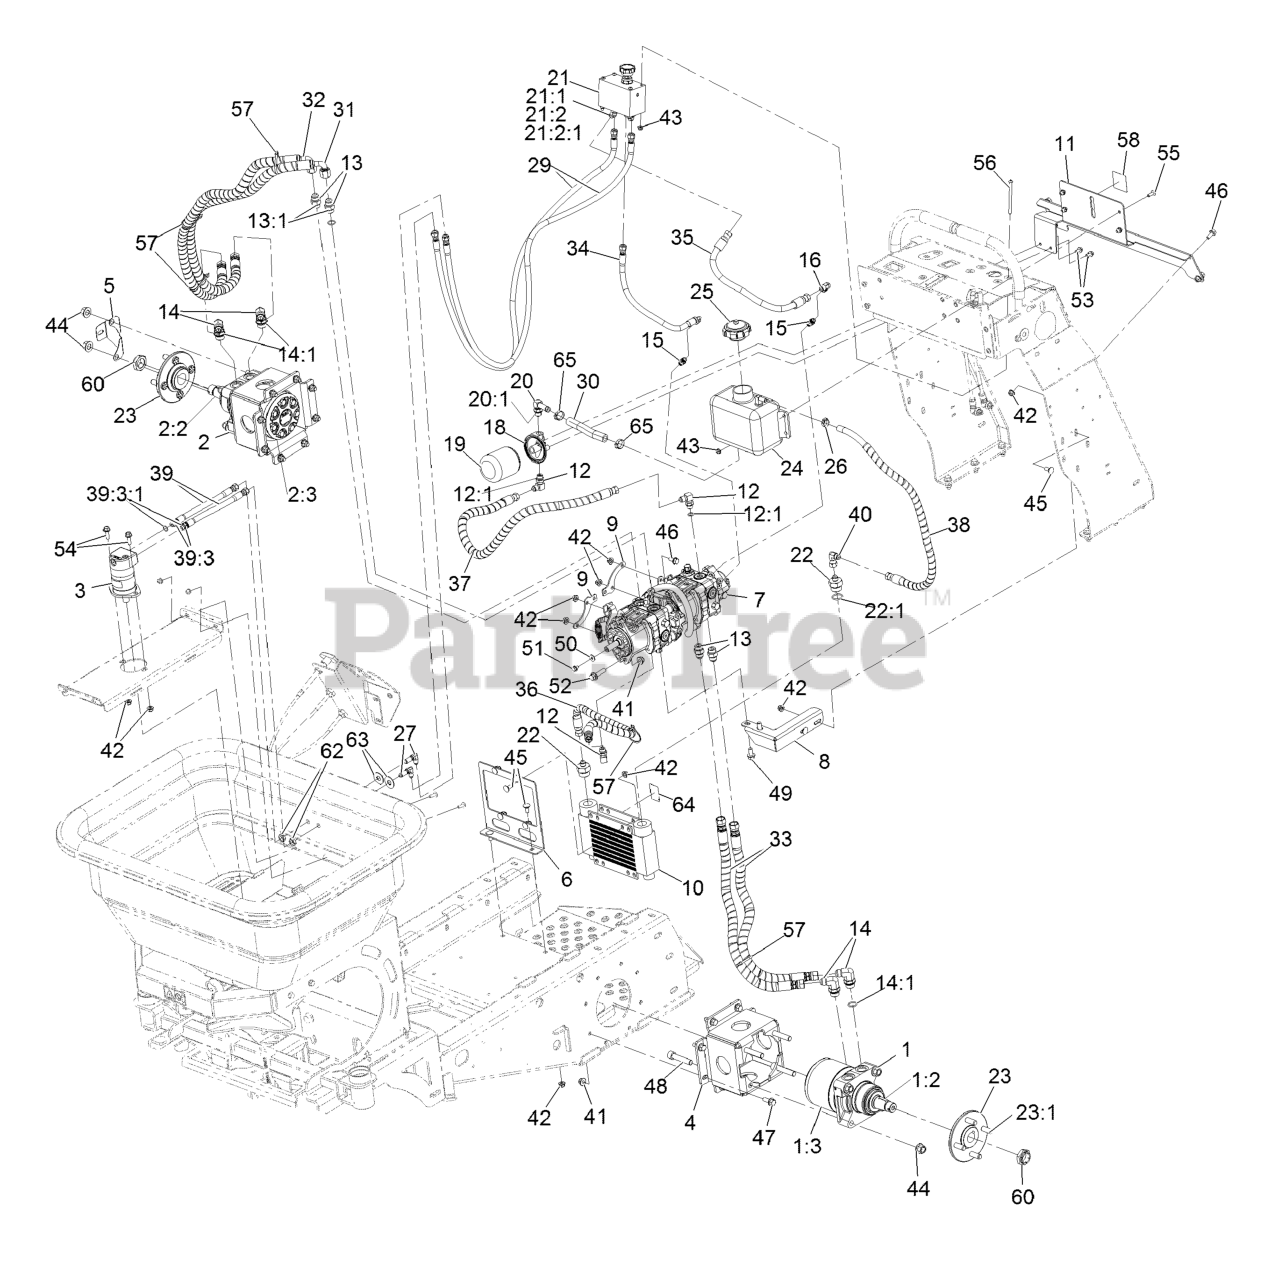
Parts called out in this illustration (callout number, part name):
1	MOTOR, LH WHEEL
1:2	KEY-WOODRUFF
1:3	SEAL KIT
2	MOTOR, RH WHEEL
2:2	KEY-WOODRUFF
2:3	SEAL KIT
3	MOTOR-HYDRAULIC, SPREADER
4	Mount-Motor, Wheel [black]
5	BRACKET-HOPPER, SPEEDOMET
6	Mount-Cooler
7	PUMP-TANDEM
8	Bracket-Support, Hydro Pump
9	Extension, Hydro Pump
10	COOLER-OIL
11	Mount, Hydraulic Tank And Filter
12	FITTING-ELBOW, 90 DEG
12:1	O-RING
13	FITTING-STRAIGHT
13:1	O-RING
14	FITTING-90 DEG
14:1	O-RING
15	FITTING-STRAIGHT
16	FITTING-90 SWIVEL
18	HEAD-FILTER
19	FILTER-25 MICRON, BI-DIRECTIONAL
20	FITTING-ELBOW, 90
20:1	O-RING
21	Manifold-Flow Control, Hopper
21:2	FITTING-ELBOW, 45 DEG
21:2:1	O-RING
22	ADAPTER-STRAIGHT
22:1	O-RING
23	HUB-WHEEL
23:1	STUD-1/2-20 X 1.55
24	TANK-HYDRAULIC, PLASTIC
25	Cap-Vented
26	CLAMP-OETIKER, 167
27	FITTING-ELBOW, 90
29	Hose ASM, HYD HP
30	HOSE-HYDRAULIC
31	HOSE ASM-HYD HP
32	Hose ASM-HYD HP
33	Hose ASM-HYD HP
34	Hose ASM-HYD HP
35	Hose ASM, HYD LP
36	Hose ASM, HYD LP
37	Hose ASM, HYD LP
38	Hose ASM, HYD LP
39	Hose ASM-HYD HP
39:3	Fitting-Straight, Rigid
39:3:1	O-RING
40	ELBOW-SWIVEL, 90 DEG
41	Nut-Hex Flange
42	Nut-Hex Flange
43	Nut-Hex Flange
44	Nut-Lock 1/2-13
45	SCREW-CARR
46	SCREW-HHF
47	SCREW-HHF
48	Screw-HSH
49	SCREW-HHF
51	SCREW-HHF
52	SCREW-HHF
53	SCREW-HHF
54	SCREW-HHF
55	Screw-Hsbhf
56	Screw-HSBH
57	TIE-CABLE
58	DECAL-OIL
60	LOCKNUT
62	Nut-Jam
63	Washer-SS, 1.25 OD, .503 ID
64	DECAL-WARNING
65	CLAMP-OETIKER, 167
